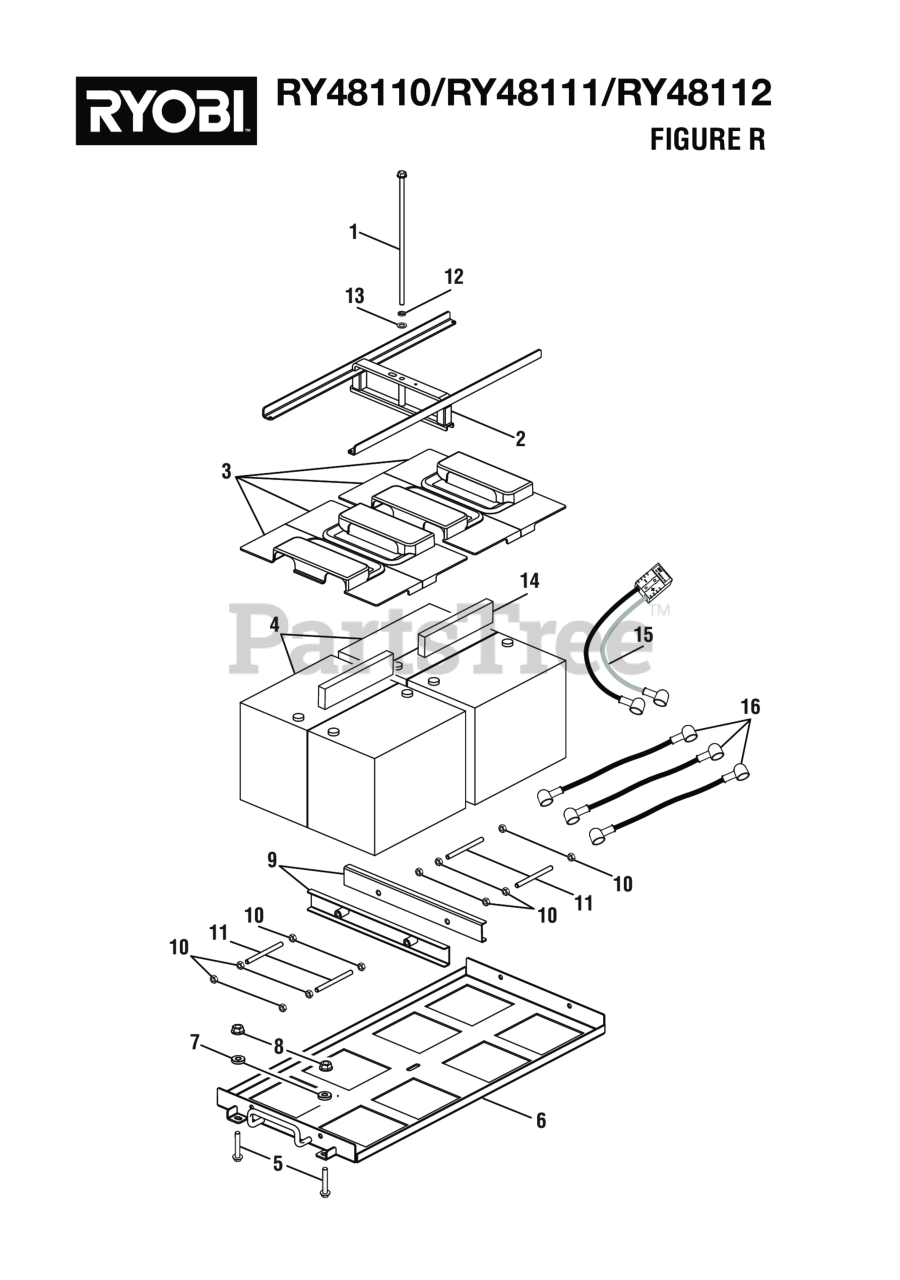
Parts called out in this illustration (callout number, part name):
1	Bolt (M8)
2	Battery Tie Down
3	Battery Cover
4	Battery (LPC12-75, RY48110, RY48112)
5	Bolt (M8 x 55 mm, Flange Hex Hd.)
6	Battery Tray
7	Metal Bushing
8	Flange Nut (M8) (For Drive Motor Controller V)
9	Battery Holder Bracket
10	Hex Nut (M8)
11	Threaded Rod (M8 x 100 mm)
12	Lock Washer (OD9.8 x ID8.5 x 5t)
13	Washer (OD12.5 x ID8.4 x 4t)
14	Battery Spacer (LPC12-75)
15	Two Wire Battery Cable (4 AWG Black & 4 AWG Red, 250 mm)
16	Battery Cable w/Covers (Red and Black, 120 mm)
